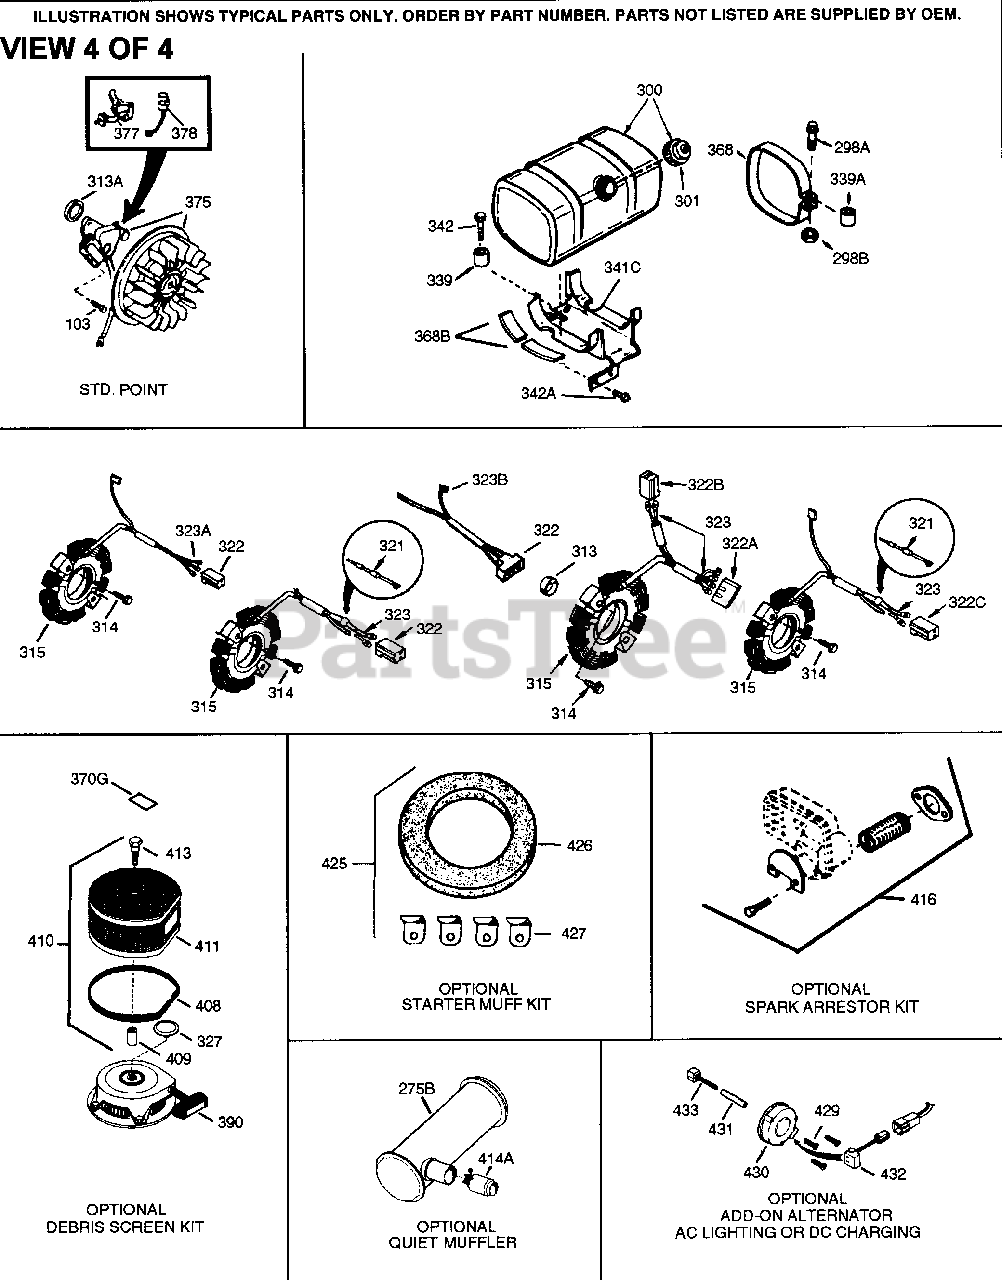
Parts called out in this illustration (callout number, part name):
103	Screw, Torx T-15, 10-24 x 1"
110A	Oil Shut-Down Wire & Terminal
129	Screw, 5/16-18 x 1-3/4"
131A	Screw, 1/4-20 x 5/8"
174A	Screw, 10-24 x 5/8"
327	Starter Plug
342	Screw, T-30, 1/4-20 x 1/2"
390	Rewind Starter NOTE: This engine cou ld have been built with 590704 starte r. Refer to the design of the air int ake louvers for part identification. Individual starter parts do not inter change.
416	Spark Arrestor Kit (Incl. 417)
417	Screw, 5/16-18 x 2-3/4"
